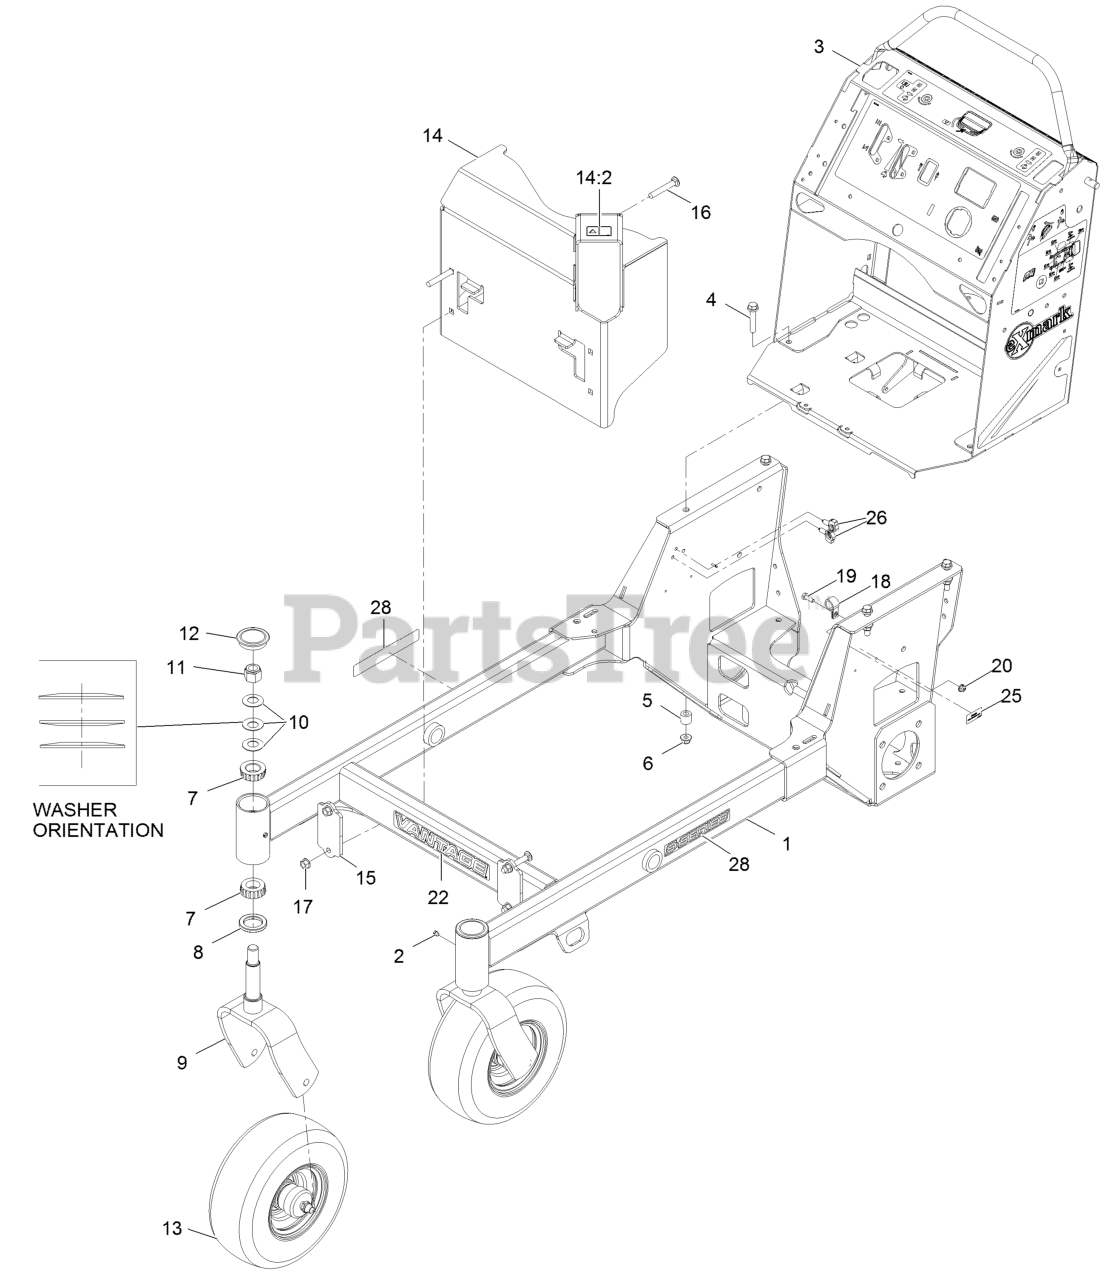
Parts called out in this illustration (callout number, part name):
1	FRAME ASM
3	CONTROL TOWER ASM
4	SCREW-HHF
6	NUT-HF, NI
7	Cone-Bearing Tapered Roller
8	SEAL-GREASE
9	FORK-CASTER
10	WASHER-BELLVILLE
11	NUT-LOCK, NI
12	CAP-GREASE
13	WHEEL/TIRE AND BEARING AS
14	MUFFLER GUARD ASM
14:2	DECAL-WARNING
15	BRACKET-MOUNTING, GUARD
16	SCREW-CARR
18	CLAMP-CABLE
19	SCREW-HH
22	DECAL-VANTAGE LOGO
25	Decal-Patent
26	CLIP-HARNESS
28	DECAL-S-SERIES
